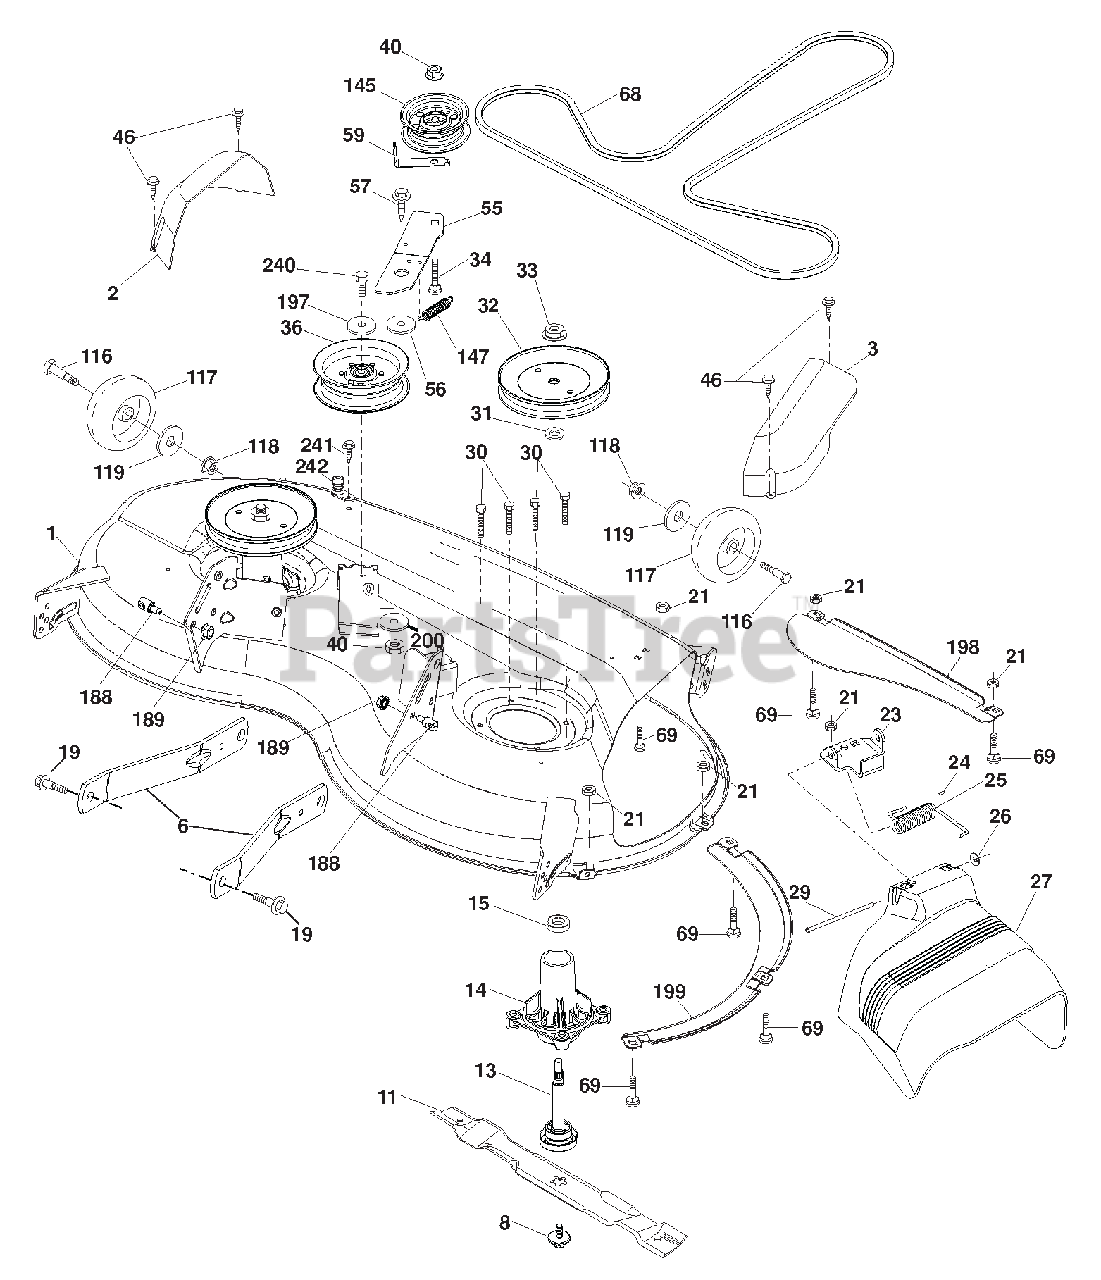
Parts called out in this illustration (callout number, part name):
1	MOWER HOUSING
2	COVER.MANDREL.LH.46"
3	COVER.MANDREL.RH.46"
6	ARM.SUSPENSION.MOWER.REAR.LD
8	BOLT/WASHER ASM.7/16-20.UNF
11	BLADE.MOWER.46"HI LIFT BAGGER
13	SHAFT ASM.MNDRL.N/GREASEABLE38
14	HOUSING.MANDREL.4PT.SERVICE
15	BEARING.BALL.MANDREL
19	BOLT.SHOULDER
21	Nut, Hex, Crownlock 5/16-18
23	BRACKET.DEFLECTOR.38/42"2005
24	CAP.SLEEVE..80X.112.BLK.MOWER
25	SPRING.TORSION.DFL.38/42/46.GR
26	NUT.PUSH.PHOS.& OIL
27	SHIELD.DEFLECTOR.MOWER 46"BLK
29	ROD.HINGE.42/46"
30	SCREW.THD ROLL.DOD PT.HEX
31	WASHER.SPACER.MANDREL
32	PULLEY.MANDREL.5.438 PD.42"
33	NUT.FLANGE.LOCK.TOP
34	BOLT.CARR.SH.3/8-16X1-1/2.GR5
36	PULLEY.IDLER.4.50.RAW
40	Nut, Hex, Flangelock 3/8-16
46	SCREW.THD.ROLL.1/4-20 X 5/8
55	IDLER.ARM
56	SPACER.RETAINER
57	SCREW.3/8-16X1.SMGML.TAP/R.BLK
59	GUARD.TUV.IDLER
68	V-BELT.DRIVE.MWR.MECHANICL.46"
69	BOLT.5/16-18HEX.WHS.HD.LCKSERR
116	BOLD SHLD "A" 2.41 "B" 1.66
117	WHEEL.GAGE.HALF.SPOKED
118	Nut, Hex, Flangelock 3/8-16
119	Washer 3/8 x 7/8 x 14 Ga.
145	PULLEY.IDLER 48"PRIMARY
188	STUD.FASTNER.W/'D'ANTI-ROTATIO
189	Nut, Lock Hex Flange 5/16-18 u
197	Washer 13/32 x 13/16 x 12 Ga.
198	BAFFLE.CENTER.FRONT
199	BAFFLE.FRONT.RH
200	WASHER.13/32 X 1 X 1/2.11GAHRD
240	BOLT.FIN.HEX.3/8-16X 2-1/4 GR5
242	PORT WASHOUT
